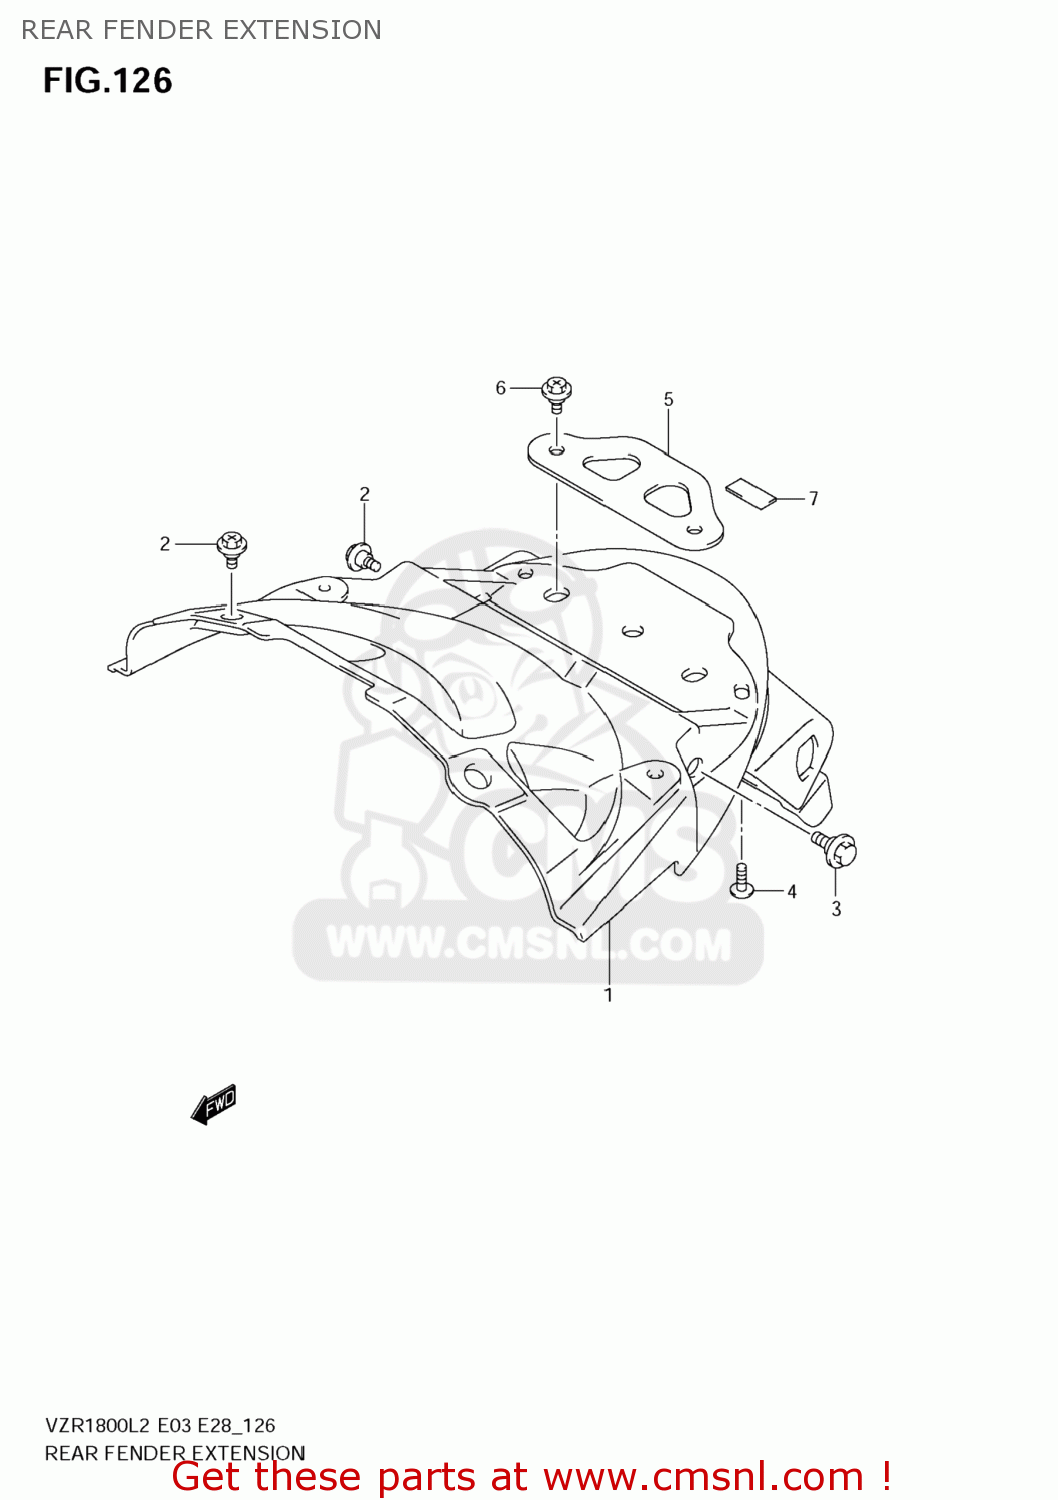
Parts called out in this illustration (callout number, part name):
1	EXTENSION,RR FENDER
2	BOLT
3	BOLT(6X16.5)
4	SCREW
5	PLATE,RR FENDER EXTENSION
6	BOLT(6X10)
7	CUSHION,RR FENDER EXT PLATE
